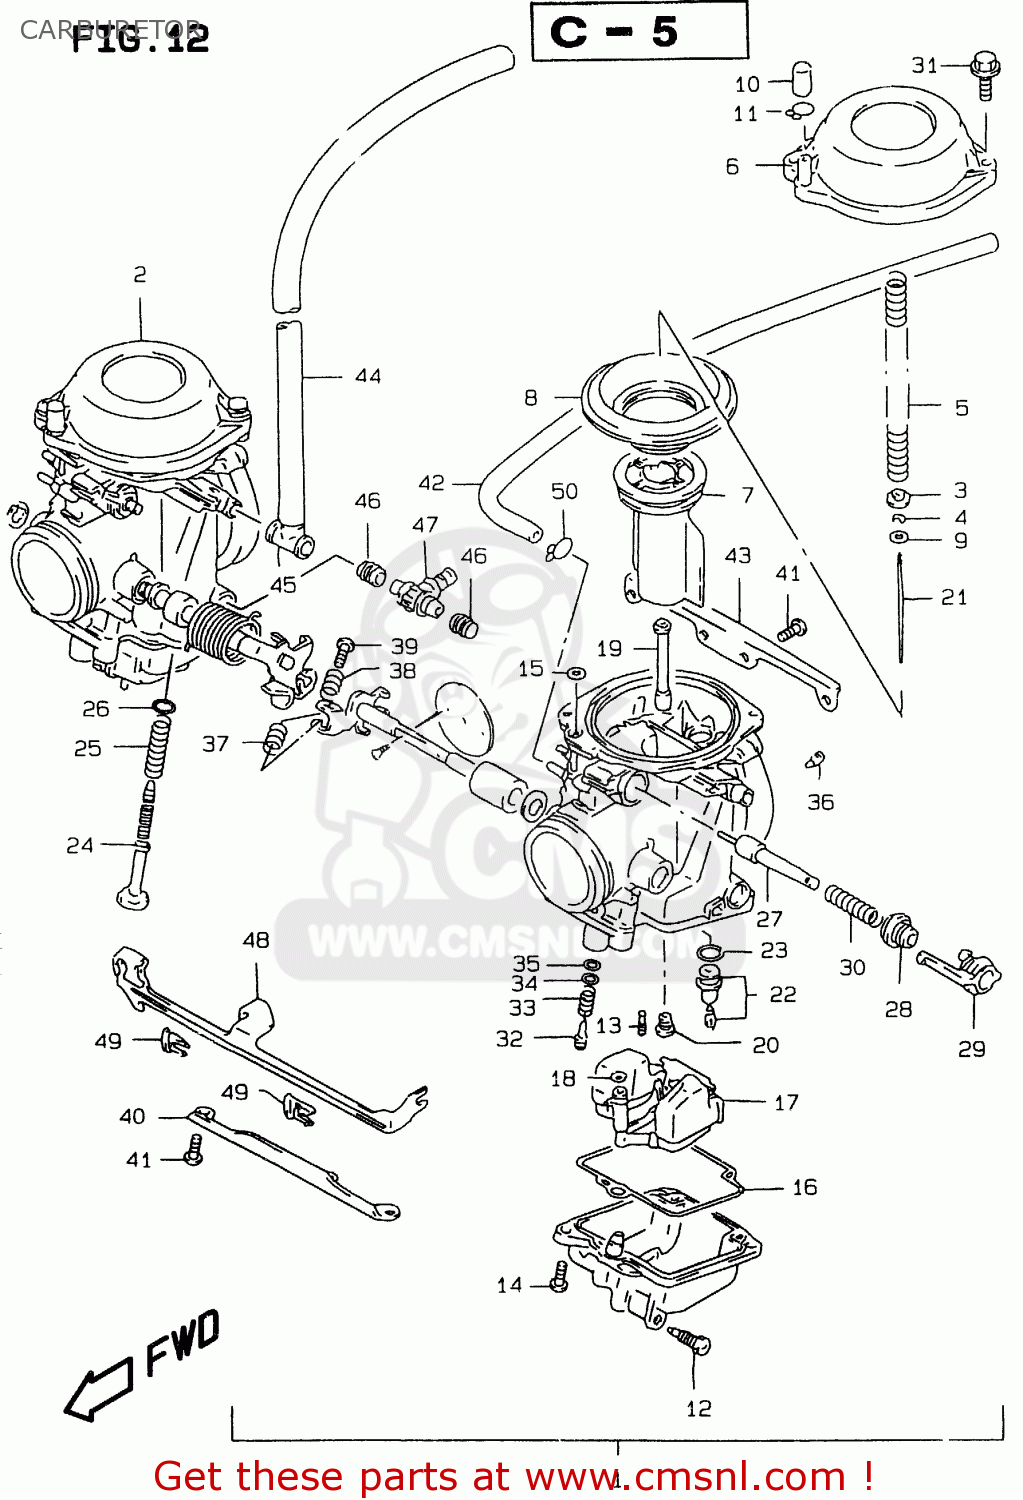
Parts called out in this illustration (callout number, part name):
1	CARBURETOR,LH
2	CARBURATOR ASS
3	RING
4	E RING
5	SPRING
6	COVER,DIAPHRAGM
7	VALVE,PISTON
8	DIAPHRAGM
9	RING
10	CAP
11	CLIP
12	SCREW,DRAIN
13	JET(40)
14	SCREW
15	O RING
16	GASKET,FLOAT CHAMBER (NAS)
17	FLOAT ASSY
18	O RING
19	JET,NEEDLE(O-2)
20	JET,MAIN(115)
21	NEEDLE,JET
22	VALVE ASSY,NEEDLE
23	O-RING,NEEDLE VALVE
24	SCREW,ADJUSTER
25	SPRING
26	WASHER
27	PLUNGER ASSY
28	CAP,STARTER
29	HOLDER,GUIDE
30	SPRING
31	SCREW
32	SCREW,PILOT
33	SPRING
34	WASHER
35	O RING,PILOT AIR SCREW
36	JET,AIR(1.3)
37	SPRING,THROTTLE SCREW
38	SPRING
39	SCREW
40	PLATE
41	SCREW
42	HOSE(5X9X350)
43	PLATE
44	HOSE(7X11X600)
45	HOSE
46	SEAL
47	NIPPLE
48	LEVER
49	HOLDER
50	CLIP
